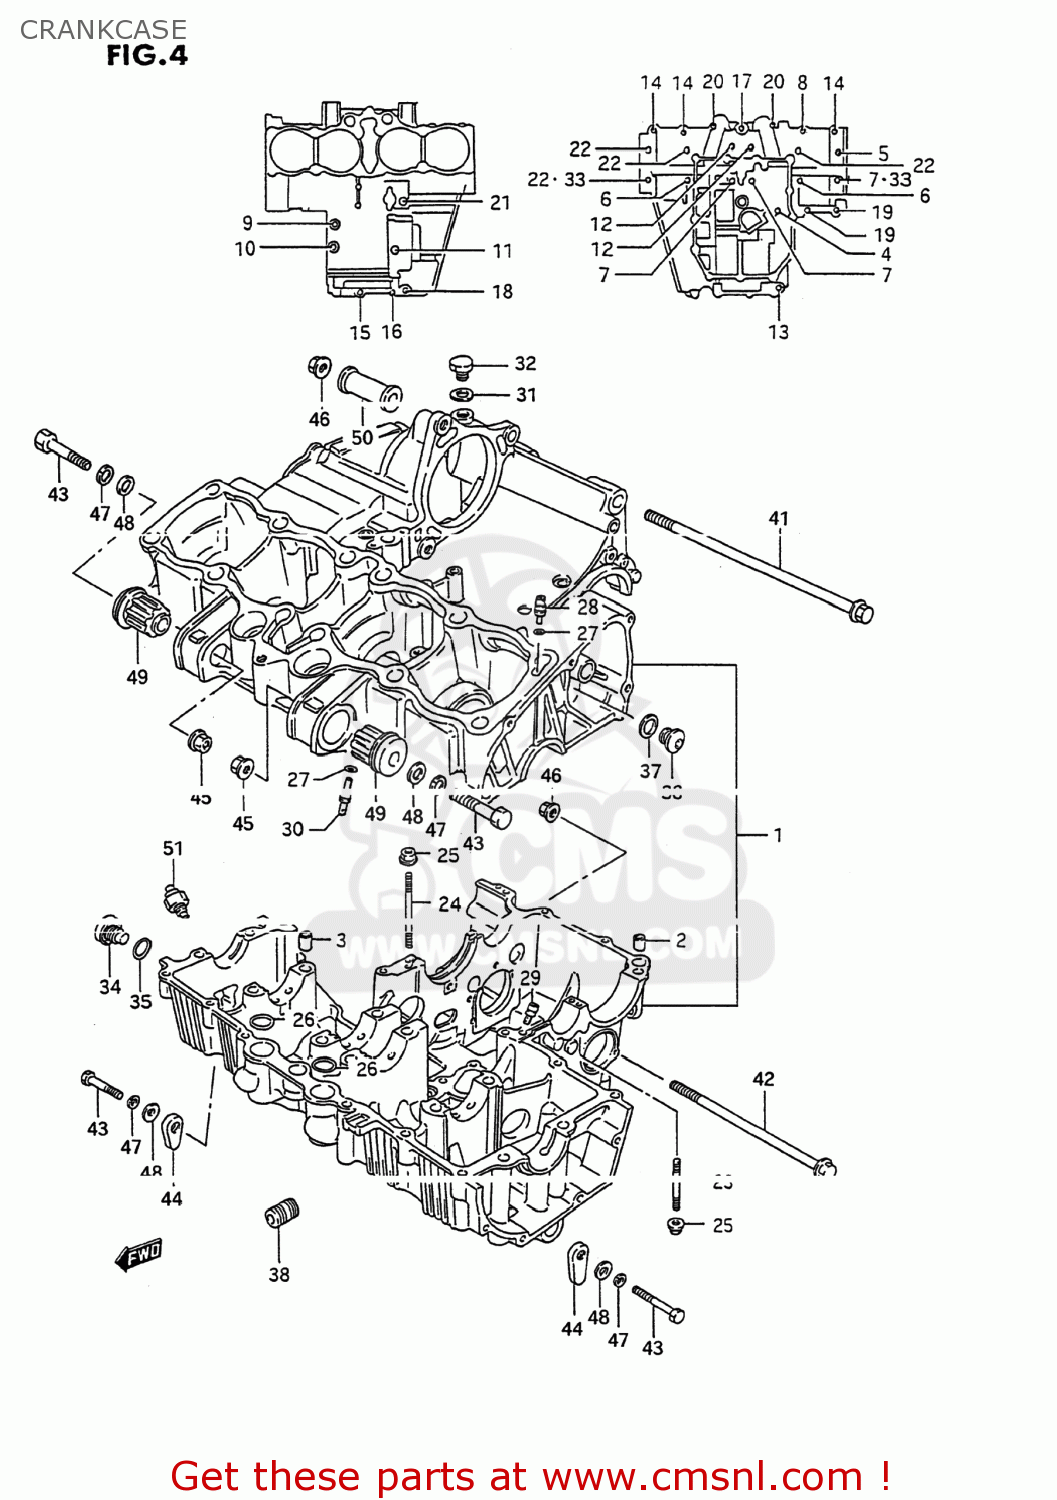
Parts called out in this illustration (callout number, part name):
1	CRANKCASE SET
2	PIN(10.4X13X22)
3	PIN (11X20)(SUS)
4	BOLT(6X105)
5	BOLT(8X105)
6	BOLT(8X125)
7	BOLT(8X115)
8	BOLT
9	BOLT
10	BOLT
11	BOLT
12	BOLT
13	BOLT
14	BOLT
15	BOLT
16	BOLT
17	BOLT
18	BOLT
19	BOLT
20	BOLT
21	BOLT
22	BOLT(8X95)
23	STUD BOLT
24	STUD BOLT
25	NUT
26	O RING(D:2.5,ID:21)
27	O RING(D:1.2,ID:4)
28	JET,AIR
29	JET
30	JET,OIL GALLERY
31	GASKET(12.1X16.2X3.7) (NAS)
32	PLUG(12X9)
33	GASKET(8.5X17X2.3) (NAS)
34	PLUG
35	O RING(D:2.4,ID:16.8)
36	PLUG,14X12
37	GASKET(13.8X18.8X4.8) (NAS)
38	UNION,OIL STAND
39	PLATE,CRANK THRUST
40	PLATE,CRANK THRUST
41	BOLT(10X175)
42	BOLT(10X130)
43	BOLT
44	NUT
45	NUT
46	NUT
47	WASHER,LOCK
48	WASHER 10MM
49	BUSH,ENGINE MOUNTING
50	SPACER,ENGINE MOUNT
51	SWITCH ASSEMBLY,OIL PRESSURE
